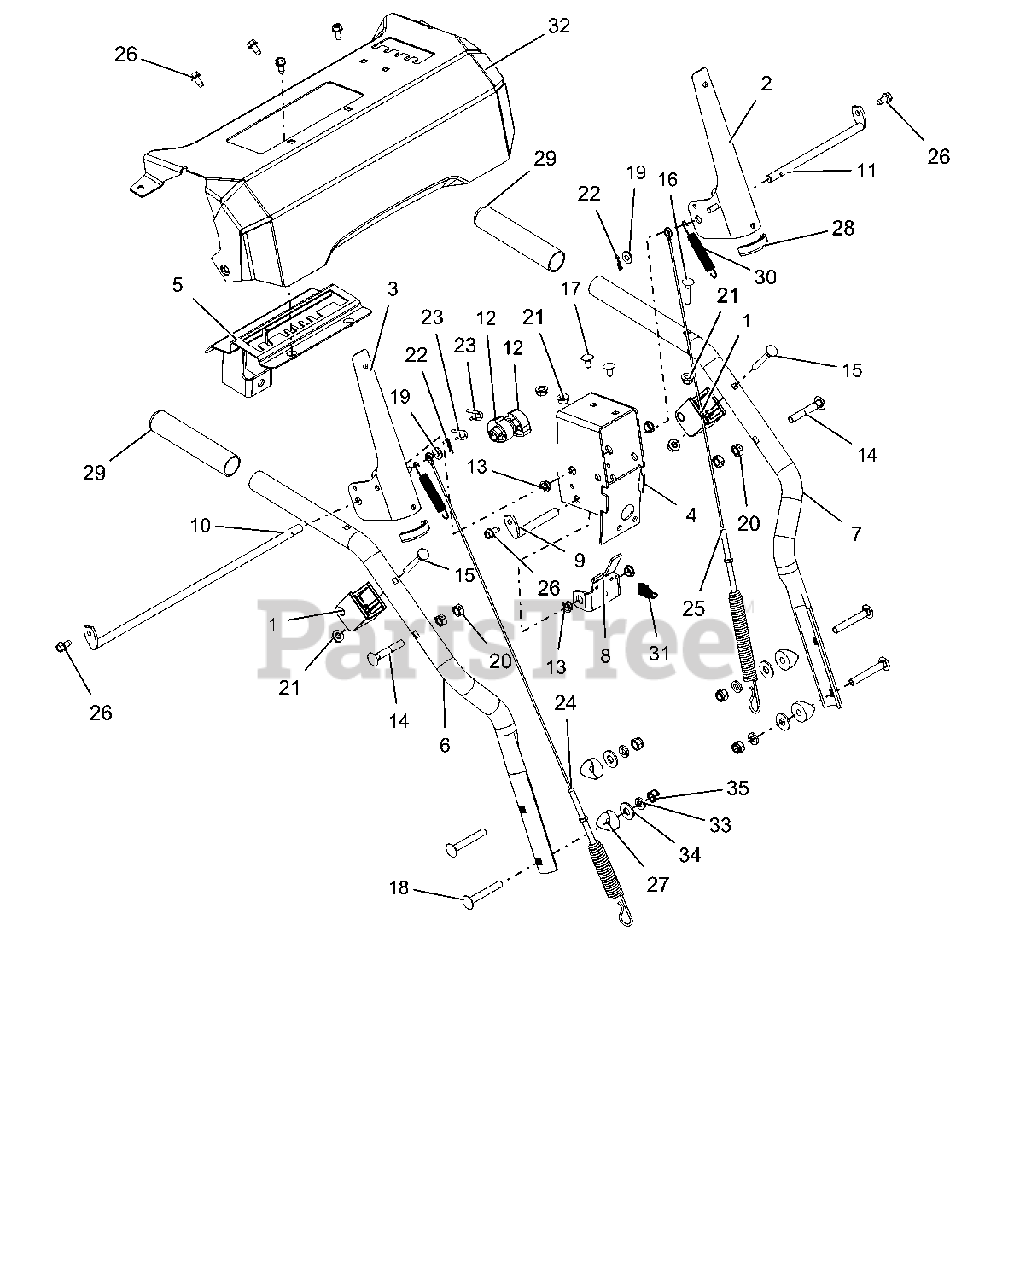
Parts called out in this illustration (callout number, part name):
1	BLOCK, CLUTCH HANDLE
2	WLDMT, CLUTCH HANDLE - LH
3	WLDMT, CLUTCH HANDLE - RH
4	WLDMT, BRKT - INTERLOCK
5	WLDMT, DETENT PLATE-COMPACT
6	HANDLEBAR, UPPER - RH
7	HANDLEBAR, UPPER - LH
8	BRKT, INTERLOCK ARM
9	ROD, PIVOT - INTERLOCK
10	ROD, PADDLE MOUNT - LONG
11	ROD, PADDLE MOUNT - SHORT
12	CAM, INTERLOCK
13	BSHG, POLYLINER-.38 SNAPIN
14	BLT, RDHD XLSQNK .31-18X2.0 G5YZ
15	BLT, RDHDXLSQNK .25-20X2.0 G5YZ
16	BLT, RDHDXLSQNK .25-20X1.25 G5YZ
17	BLT-RDHDSQNK .25-20X.50 G5 Y
18	BLT-RDHDSQNK .31-18X2.25 G5 Y
19	WSHR-FL-STL.281X.62X.065 YWZC
20	NUT-LK-CTR .31-18 YWZC
21	NUT, LK-TOP-FLG .25-20 YWZC
22	PIN-HAIR INT .06X.18X.77
23	PIN, SPRING CLIP
24	CABLE, AUGER (DELUXE & PRO)
25	CABLE, UPPER TRACTION
26	SCR-TAP .25-20X.50 HWH TR YWZ
27	SPCR, HANDLEBAR
28	STRIP, EDGE - CLUTCH HANDLE
29	GRIP, HANDLE
30	SPRG, EXTENSION
31	SPRG, EXTENSION
32	PANEL, CONTROL - W/DECAL 08000736
33	WSHR-LK .31X.097 HVY YWZC
34	WSHR-FL-STL.38X.875X.083 YWZC
35	NUT-LK-NYL .312-18 YWZC
